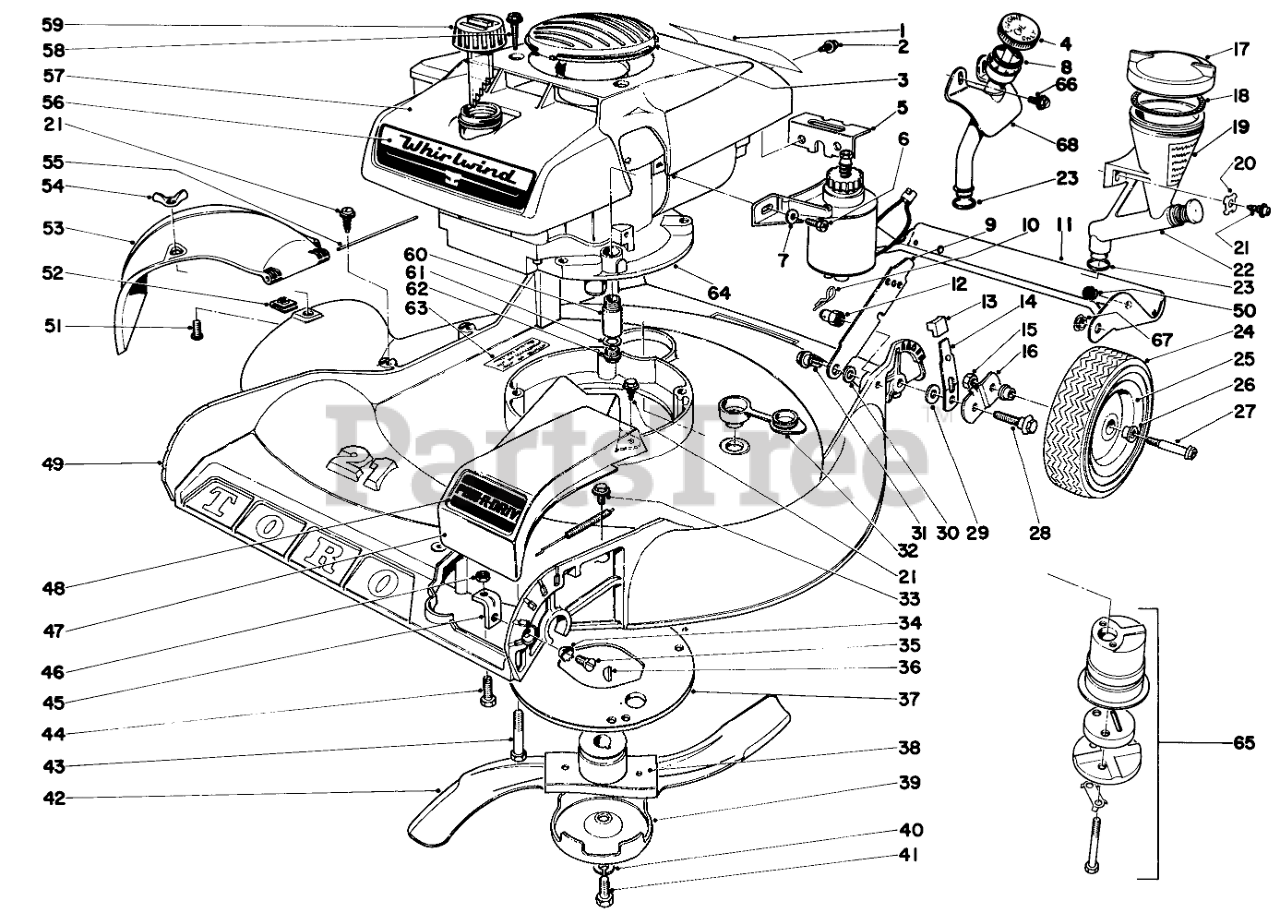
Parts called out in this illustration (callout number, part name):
1	Decal,Maintenance
2	SCREW-HWHTF
3	Insert Shroud
4	Dipstick
5	Bracket
6	SCREW-HH
7	WASHER-FLAT
8	O-Ring
9	Latch
10	PIN-COTTER, HAIR
11	Safety Shield, Rear
12	Nut
14	Spring Arm
15	Nut
16	Pivot Arm
17	Cap, Reservoir (Incl. Ref.18)(Used on Model No.21104)
18	"O" Ring
19	Decal, Reservoir
20	Washer
21	Screw
22	Reservoir, Oil
23	O-RING
24	8 TIRE
25	Wheel Assy. (Incl. Ref. 26)
26	FLANGE BUSHING
27	Wheel Bolt
28	Pivot Screw
29	WASHER-PIVOT
30	SPACER
31	SCREW-SHOULDER
32	Washer Plug
33	Screw
34	Lockwasher
36	KEY-WOODRUFF
37	Grass Guard
38	BLADE RETAINER WA
39	ANTI-SCALP CUP
40	WASHER-LOCK
41	SPECIAL SCREW
42	Blade
43	Screw
44	SCREW
45	ADJ BRACKET
46	NUT-JAM
47	Guard, Belt
48	Decal
49	Housing
50	SKID BUTTON
52	NUT-SPEED
53	Deflector
54	NUT-WING SPECL
55	HINGE PIN
56	Decal
57	Shroud
58	SCREW-HWH
59	Gas Cap
60	Extension Oil Drain
61	Gasket-Oil Drain
62	Plug Oil Drain
63	Decal
64	Engine (Used on Model 21666)
65	Muffler
67	Nyliner
68	Oiler Tube
